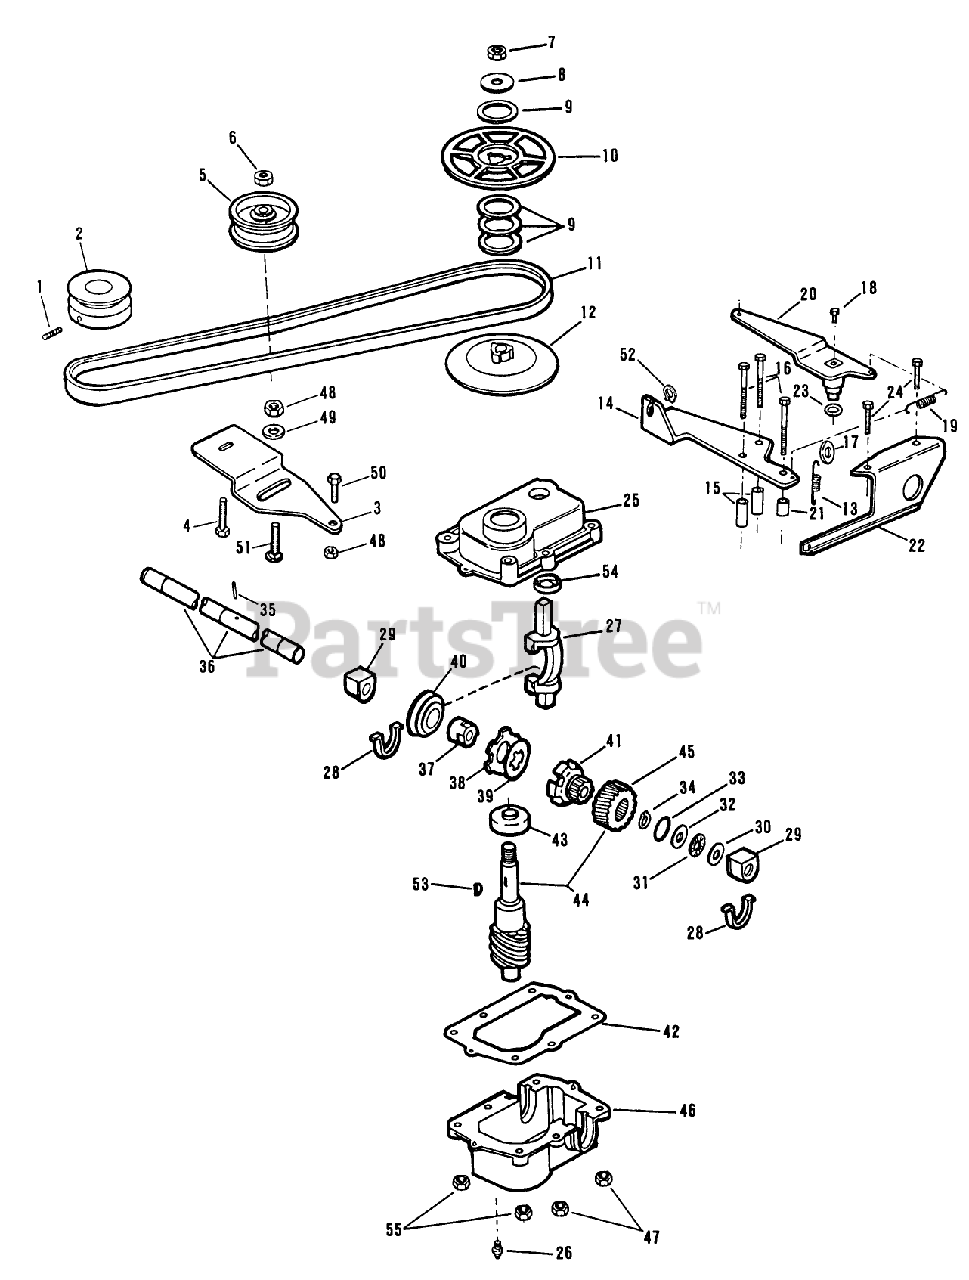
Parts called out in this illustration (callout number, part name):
1	SET SCREW F
2	PULLEY F
5	PULLEY IDLER NHI
6	NUT-JAM, LOCKING
7	LOCKNUT
8	WASHER
10	PULLEY UPPER PL
11	V-BELT F
12	PULLEY LOWER PL
13	SPRING EXTEN D&B
14	CONDUIT ANCHOR BRKT
17	WASHER
18	SCREW SEMS SM
19	SPRING
23	O-RING
27	FORK SHIFT
29	BEARING & SEAL AY (12)
30	THRUST WASHER
32	WASHER-THRUST
34	RET RING
35	PIN DRIVE LOCK
38	ORD 684683,
39	ORD KIT 684683
41	DRIVER BROCKWAY
42	GASKET HOOSIER
43	BEARING-BALL
45	WORM WHEEL
47	LOCKNUT E
48	NUT-LOCK F
52	RET. RING
53	KEY GALGER
54	GUIDE ELCO
55	LOCKNUT E
